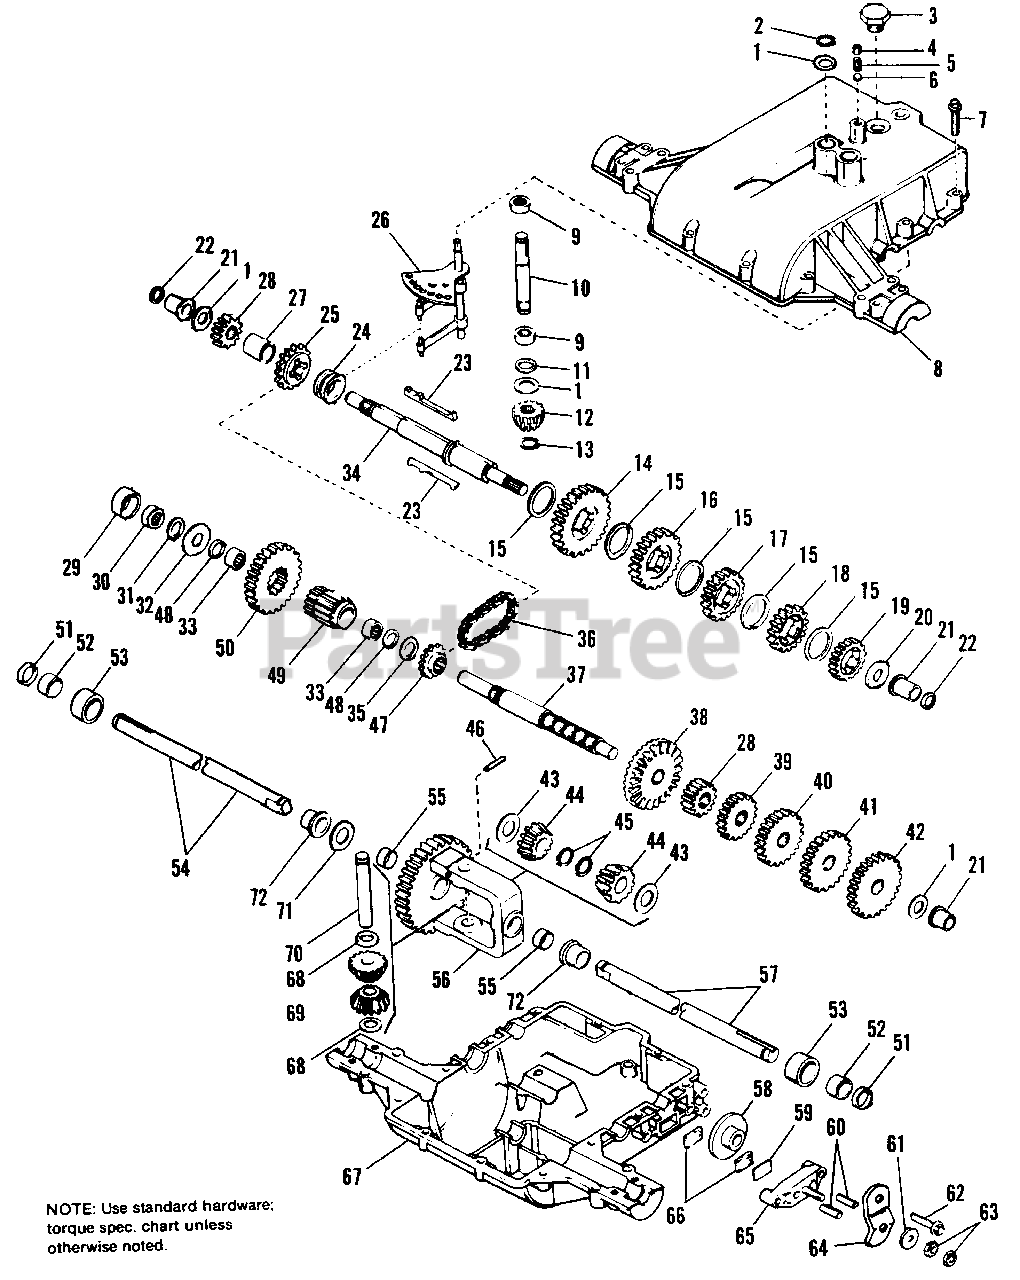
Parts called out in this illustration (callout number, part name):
1	WASHER, Thrust
2	RING, Retaining
4	SETSCREW, 3/8-16 x 3/8
6	BALL, Steel
7	SCREW, Hex Hd., Thd. Form., 1/4-20 x 1-1/4
8	COVER, Transaxle
9	BEARING, Needle
10	SHAFT, Input
11	RING, Square Cut
12	PINION, Bevel, Input
13	RING, Retaining
14	GEAR, Spur (35 Teeth)
15	WASHER, Thrust
16	GEAR, Spur (30 Teeth)
17	GEAR, Spur (25 Teeth)
18	GEAR, Spur (22 Teeth)
19	GEAR, Spur (20 Teeth)
20	WASHER, Thrust
21	BUSHING, Flanged
22	RING, Square Cut
24	COLLAR, Shift
25	SPROCKET (18 Teeth)
26	ROD & FORK ASSY., Shift
28	GEAR, Spur (15 Teeth)
30	BEARING, Needle
31	RING, Square Cut
32	WASHER, Flat
33	BEARING, Needle
34	SHAFT, Brake
35	WASHER, Flat
36	CHAIN, Roller (No. 41 chain, 24 links)
37	SHAFT, Counter
38	GEAR, Bevel (42 Teeth)
39	GEAR, Spur (20 Teeth)
40	GEAR, Spur (25 Teeth)
41	GEAR, Spur (28 Teeth)
42	GEAR, Spur (30 Teeth)
43	WASHER, Thrust
44	GEAR, Bevel
45	RING, Retaining
46	PIN, Roll
47	SPROCKET (9 Teeth)
48	RING, Square Cut
49	PINION, Output
50	GEAR, Output
51	SEAL, Oil
52	BEARING, Needle
54	AXLE (12-1/8" long)
56	GEAR ASSY., Diff. (Includes 2 of No. 55)
57	AXLE (15-1/8" long)
58	DISC, Brake
59	PLATE, Brake Pad
60	PIN, Dowel
61	WASHER, Flat
62	SCREW, Hex Hd., Thd., Form., 1/4-20x 1-1/4
63	LOCKNUT, Hex, 5/16-24
64	LEVER, Brake
65	HOLDER, Brake Pad
66	PAD, Brake
67	CASE, Transaxle
68	WASHER, Thrust
69	PINION, Bevel
70	PIN, Drive
72	BUSHING, Flanged
